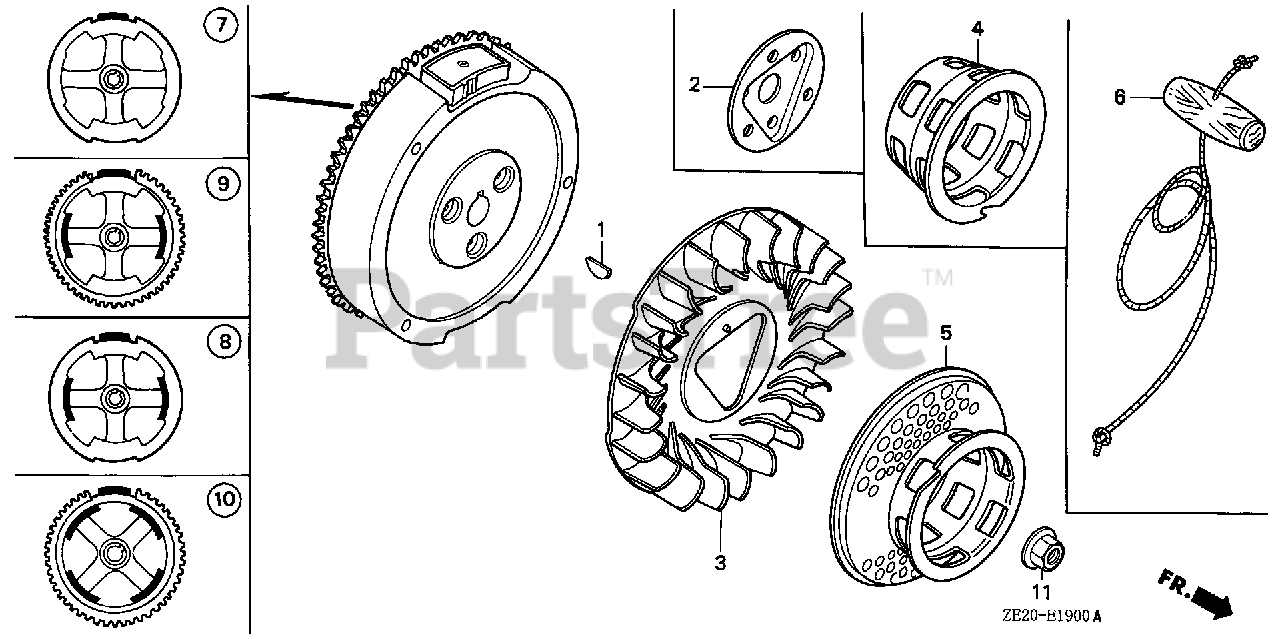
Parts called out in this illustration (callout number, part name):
1	KEY, SPECIAL WOODRUFF (25X18)
3	FAN, COOLING
5	PULLEY, STARTER
11	NUT, SPECIAL (16MM)
11	NUT, SPECIAL (16X1.5)
